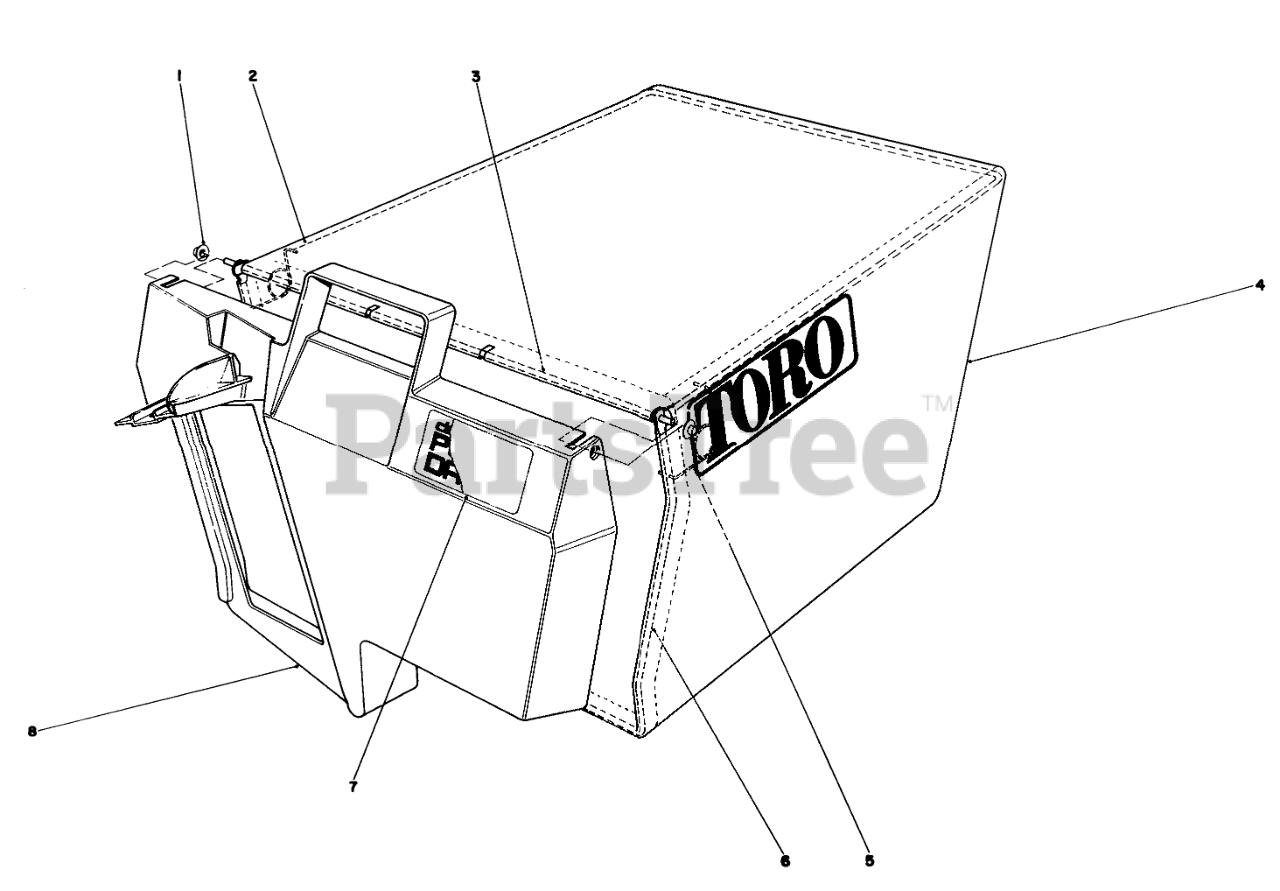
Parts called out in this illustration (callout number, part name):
1	NUT-PUSH
2	FRAME-BAG, UPPER
3	HINGE-DOOR, BAG
4	BAG-GRASS
5	SPRING
6	FRAME-BAG
7	BAG DOOR DECAL
8	DOOR-BAG
